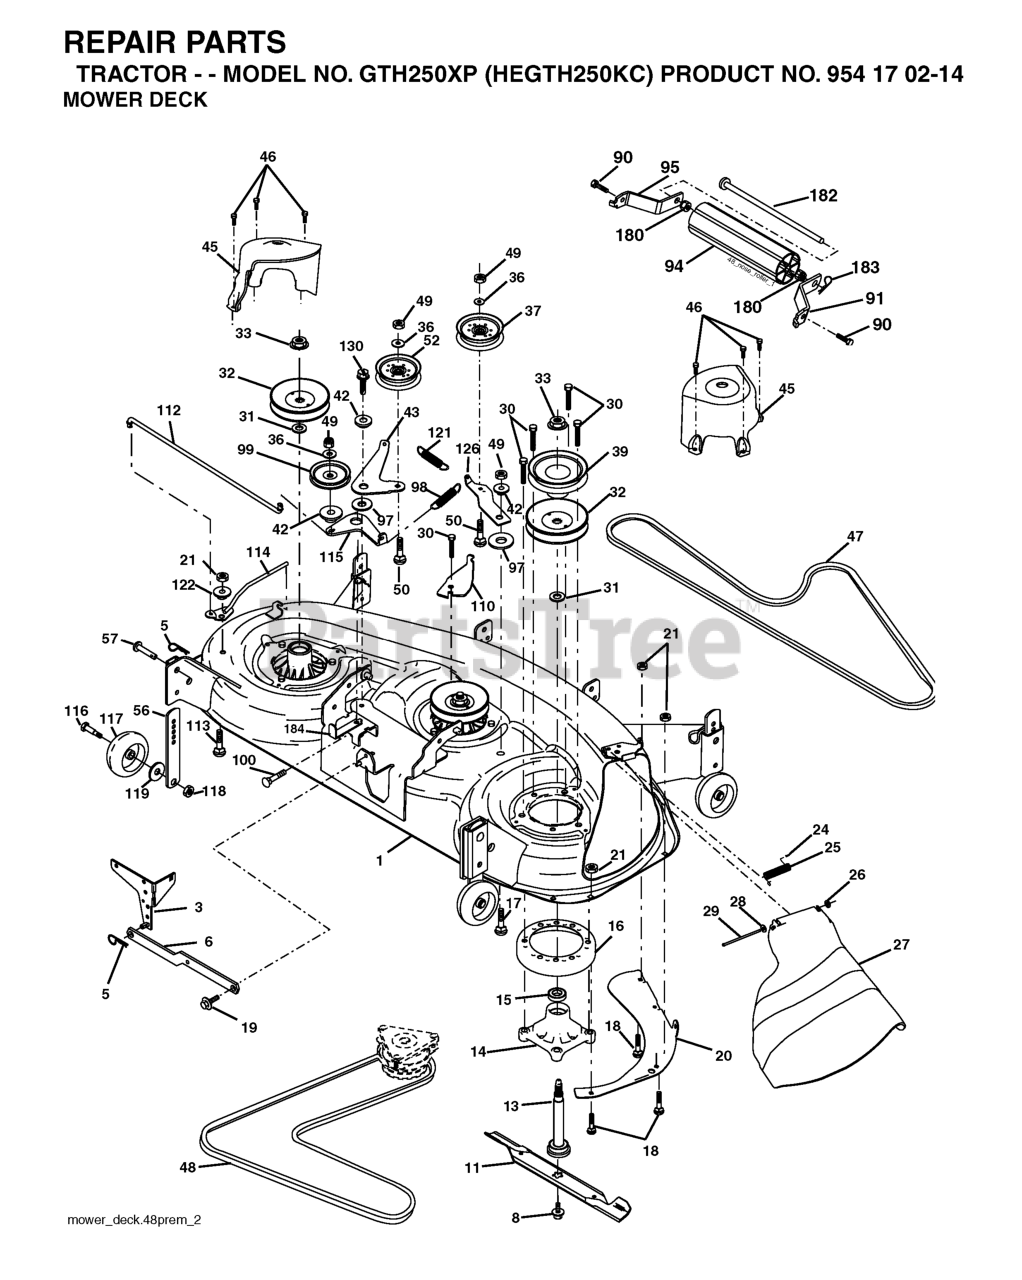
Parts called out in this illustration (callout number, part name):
1	WEIGHT.AUGER.HSG.24
2	NUT.LOCK.5/16-18
3	BOLT.CARRIAGE.5/16-18
4	PULLEY, IMPELLER
5	BEARING FLANGE
6	NUT.FLANGE.5/16
7	BOLT.CARRIAGE.5/16-18X
8	BOLT
9	BOLT, HEX HEAD 5/16-18
10	AUGER HOUSING
11	BAR, SCRAPER
12	BRACKET, CORNER DISCHARGE
13	BASE DISCHARGE CHUTE
14	WASHER.LOCK.HVY.HLCL.SPR.5/16
15	WASHER, FLAT
16	CAPSCREW.HX.HD.5/16-18X1.00.NY
17	GREASE FITTING
18	SCREW, HEX HD 5/16X1
19	LOCKNUT.NYLOC.1/4-20
20	NUT.FLANGE.5/16
22	SKID PLATE RH
25	BOLT
26	BEARING RETAINER, PLASTIC
27	WASHER TRUST 1"
28	BOLT, SHEAR
29	SKID PLATE LH
30	RP AUGER ASSEMBLY, RH
31	RP AUGER ASSEMBLY, LH
33	BUSHING, FLANGE 3/4
34	WASHER, THRUST 3/4
35	BEARING TRUST 3/4 NTA-1220
36	SHAFT, IMPELLER
37	WASHER, THRUST 5/8
38	FLANGE BUSHING-5/8
39	HEX SCREW-5/16 X 3/4
40	CASE PLUG
41	GEARBOX HOUSING-RH
42	OIL SEAL
43	FLANGE BUSHING-1"
44	KEY, SQUARE 1/4 X .875
45	WORM GEAR
46	AUGER SHAFT
47	HOUSING.GEARBOX.LH(SERVICE)
48	IMPELLER ASSY
49	SCREW.HEX.HD1/4-20X
50	GEARBOX GASKET
51	PIN, ROLL 3/16 X 1-1/8
55	SPACER.3943.SLEEVE.250X.47
56	RP WRENCH, SNOWTHROWER
57	GEARBOX.ASSEMBLY.AUGER
58	BEARING.BALL.AUGER.SHAFT
